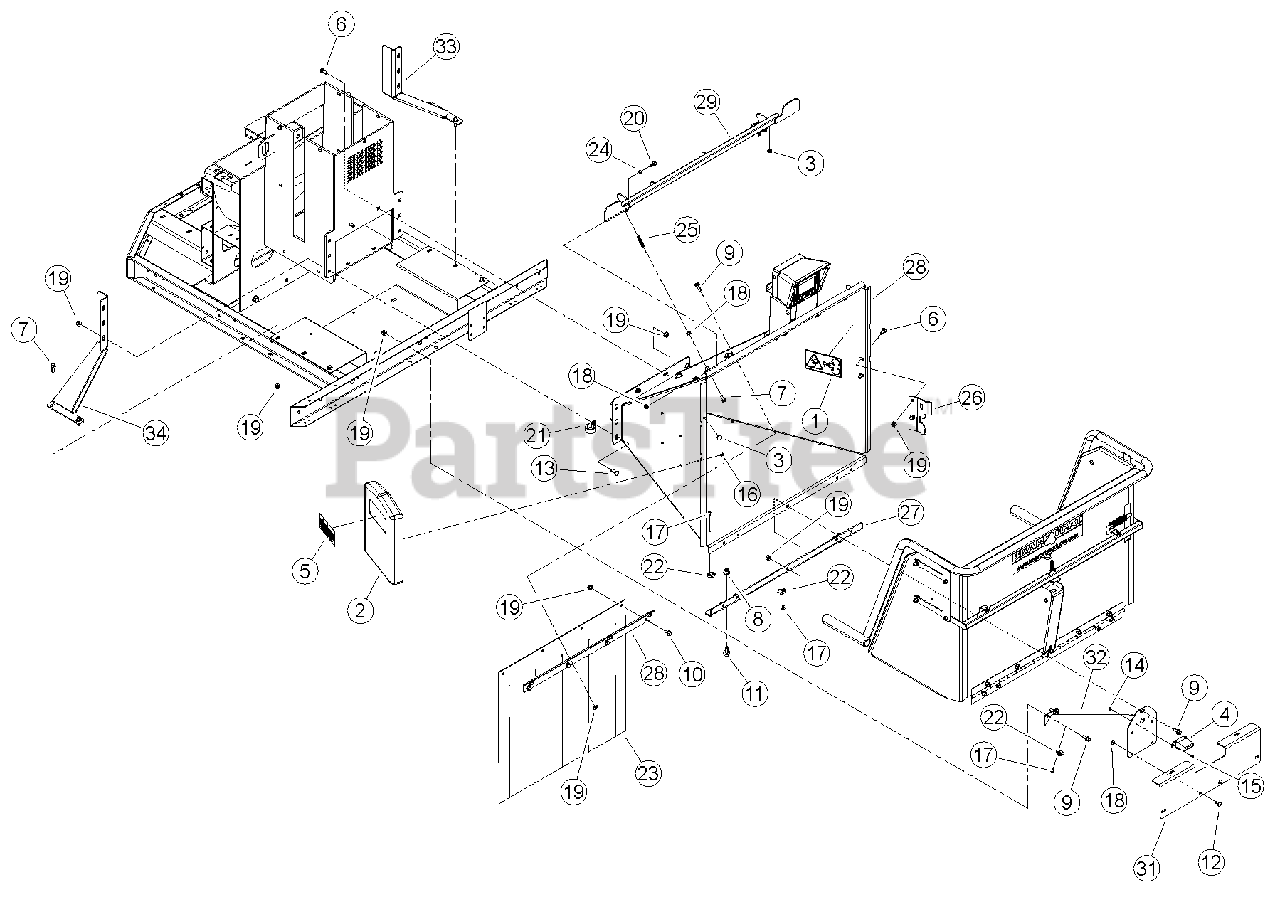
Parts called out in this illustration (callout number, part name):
1	DECAL, BLADE DANGER ISO
2	CONTAINER, INSTR. MANUAL
3	BUMPER, RUBBER
4	LIGHT, LICENSE PLATE
5	DECAL, MUTILINGUAL MANUAL
6	BOLT, 3/8 X 1" GR5 CRG NC ZP
7	BOLT, 5/16 X 3/4 FLANGE NC
8	NUT, 1/2-13 NYLOCK FLANGE
9	BOLT, 3/8 X 1 FLANGE NC
10	BOLT, 3/8 X 3/4 FLANGE NC
11	BOLT, 1/2-13 1.00 GR5 FLANGE NC
12	BOLT, 5/16 X 3/4 GR5 CRG NC ZP (CE COMPLIANT ONLY)
13	BOLT, 3/8 X 1-1/4" GR5 CRG NC ZP
14	NUT, 10/24 NYLOCK TYPE NM ZP
15	SCREW, MCH 10-24 X 1/2" PAN HD PH ZP
16	RIVET, AL BLIND 1/4 X 1/2 DOME HEAD
17	RIVET, AL BLIND 1/4 X 3/4 DOME HEAD
18	NUT, 5/16-18 NYLOCK-FLANGE
19	NUT, 3/8-16 NYLOCK FLANGE
20	BOLT, 5/16-18 X 3/4 ZP FLANGE SHOULDER
21	CLAMP, 1 9/16 COATED METAL
22	CLAMP, CABLE MOUNT
23	FLAP, CHUTE
24	BEARING, .375 X .50 X .25 LONG
25	SPRING, COMPRESSION .437 DIA X 2.0 LONG
26	PLATE, TRAY LATCH
27	ANGLE, 6" INFEED SUPPORT
28	SUPPORT, 6" CHIPPER FLAP
29	WELDMENT, 6" TOP SAFETY BAR
30	WELDMENT, 6" CHIPPER CHUTE
31	BRACKET, EUROPEAN LICENSE (CE COMPLIANT ONLY)
32	WELDMENT, CHUTE SUPPORT
33	PLATE, CHIPPER SUPPORT RH
34	PLATE, CHIPPER SUPPORT LH
